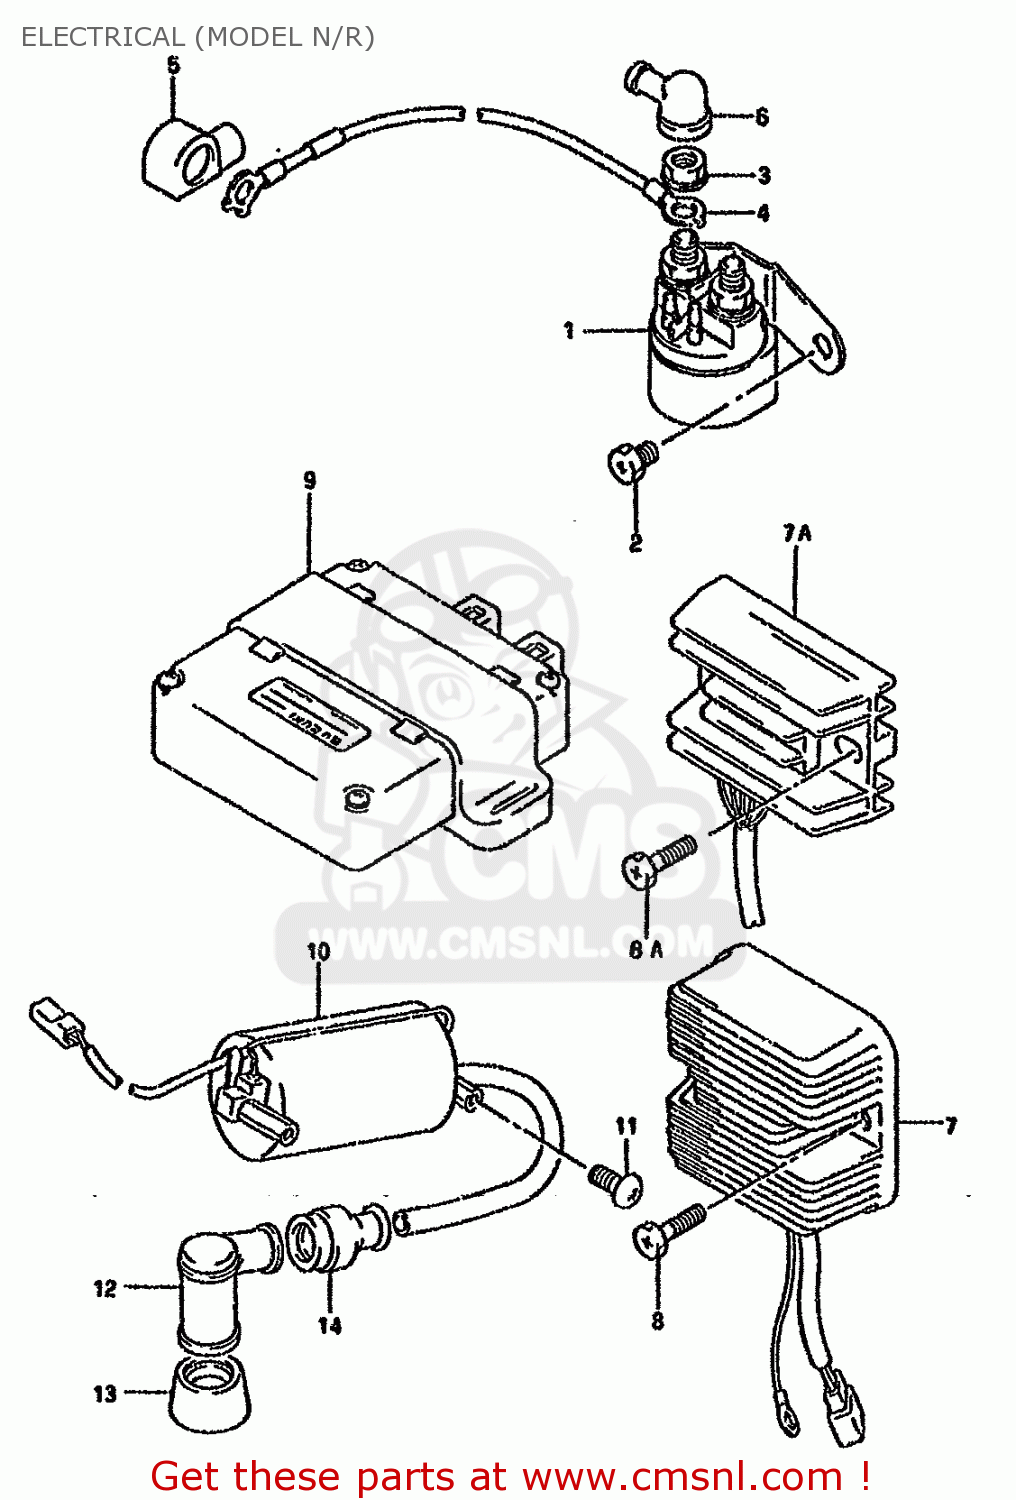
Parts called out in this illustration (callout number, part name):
1	RELAY ASSY,STARTING MOTOR
2	SCREW(6X10)
3	NUT
4	WIRE,STARTER MOTOR
5	CAP,STARTER MOTOR TERMINAL
6	CAP,TERMINAL
7	RECTIFIER ASSY
7A	RECTIFIER ASSY
8	SCREW(6X12)
8A	BOLT(6X20)
9	IGNITOR UNIT
10	COIL ASSY,IGNITION
11	SCREW
12	CAP ASSY,SPARK PLUG
13	SEAL,SPARK PLUG CAP
14	CAP ASSY,SPARK PLUG
15	SEAL,SPARK PLUG CAP
16	SEAL,HIGH TENSION CORD
